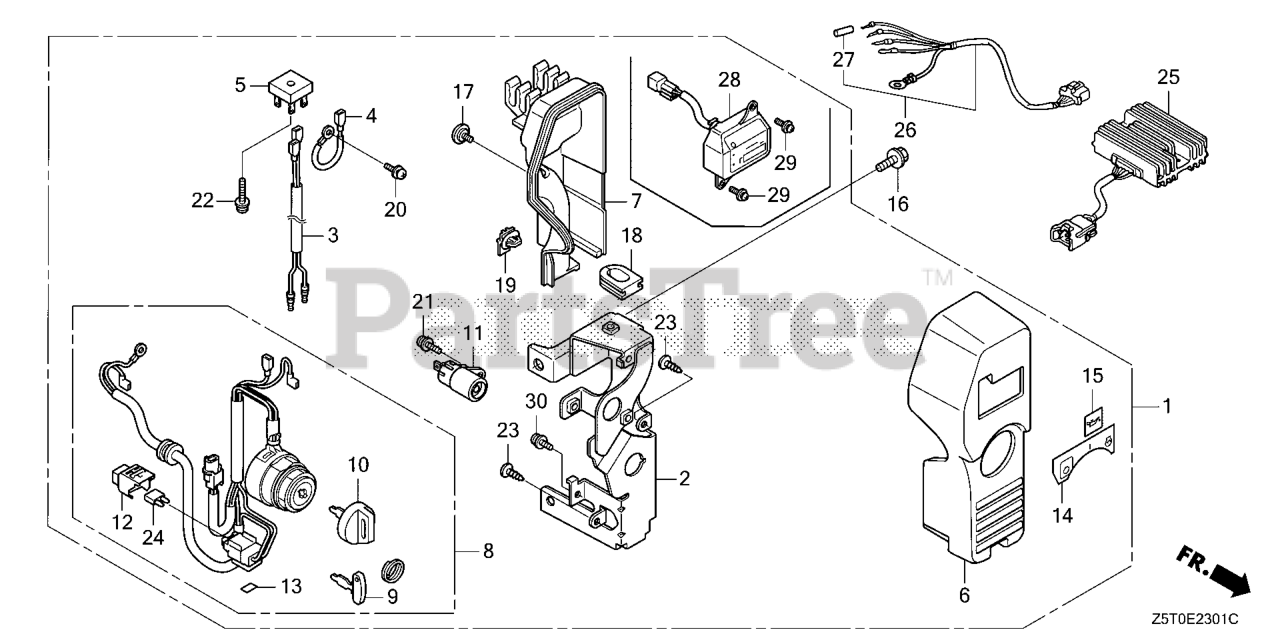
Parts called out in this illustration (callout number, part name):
1	BOX ASSY., CONTROL
2	BRACKET, SWITCH BOX
3	WIRE, CHARGE COIL
4	WIRE, GROUND
6	PANEL, CONTROL
7	COVER, CONTROL
8	SWITCH ASSY., COMBINATION (IND)
10	KEY ASSY., COMBINATION SWITCH (BLACK)
11	INDICATOR ASSY.
12	COVER ASSY., FUSE
13	LABEL, FUSE (30A)
14	MARK, ENGINE SWITCH
15	MARK, OIL CAUTION
16	BOLT, FLANGE (6X12) (CT200)
17	SCREW, SPECIAL (6X8)
18	GROMMET, CONTROL BOX
19	CLIP, CONNECTOR (BLACK)
20	SCREW-WASHER (4X8)
21	SCREW-WASHER (4X10)
22	SCREW-WASHER (4X20)
23	SCREW, TAPPING (4X14) (PO)
24	FUSE, MINI (30A)
